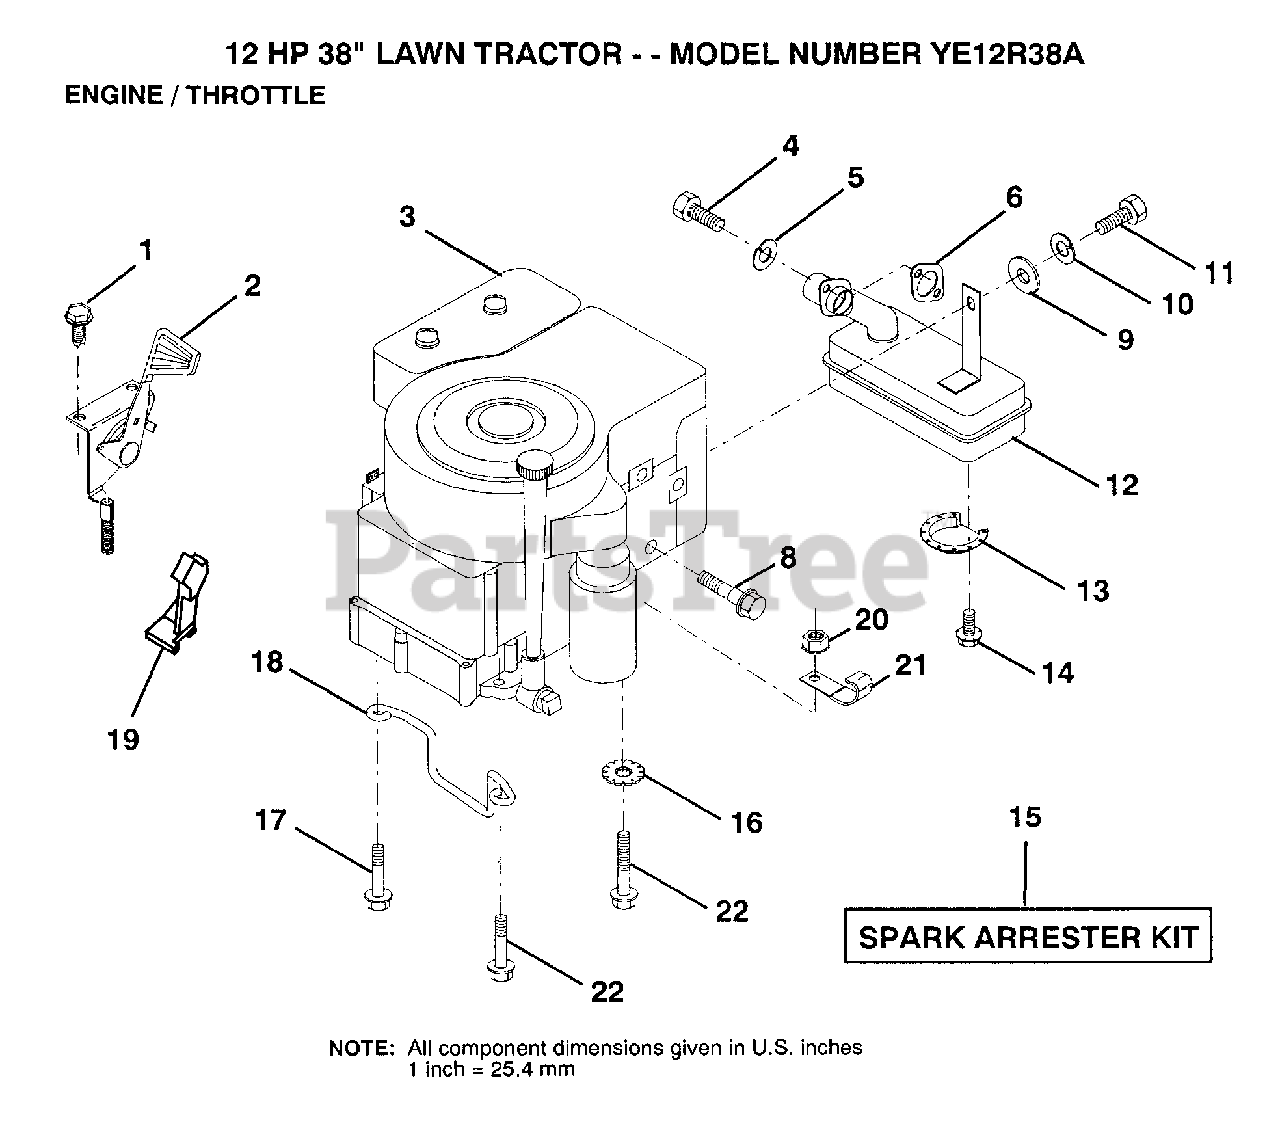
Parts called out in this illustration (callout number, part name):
1	SCREW
3	ENGINE BRIGGS AND STRATTON
4	SCREW
5	LOCKWASHER
7	NUT.HEX.5/16-18
8	BOLT T
10	LOCKWASHER
13	DEFLECTOR.222573
16	LOCKWASHER
17	SCREW LT
18	"KEEPER,DR BELT GR"
20	NUT
21	CLIP T
22	SCREW LT
